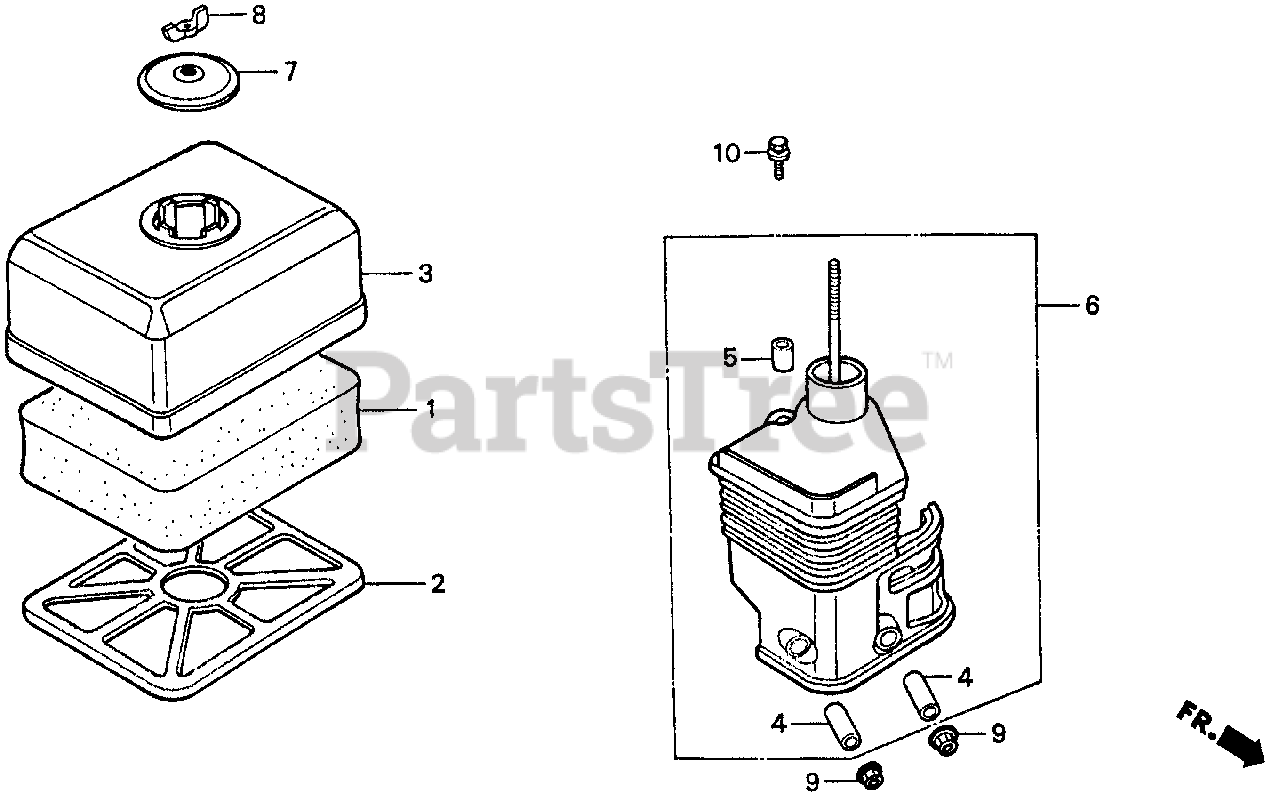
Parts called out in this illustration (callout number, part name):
1	ELEMENT, AIR CLEANER (SEMI DRY)
2	GRID, AIR CLEANER (SEMI DRY)
3	COVER, AIR CLEANER (SEMI DRY)
4	COLLAR, AIR CLEANER
5	COLLAR B, AIR CLEANER
6	ELBOW, AIR CLEANER
7	CAP, CLEANER
8	WINGNUT, TOOL BOX SETTING
9	NUT, FLANGE (6MM)
10	BOLT, FLANGE (6X20)
